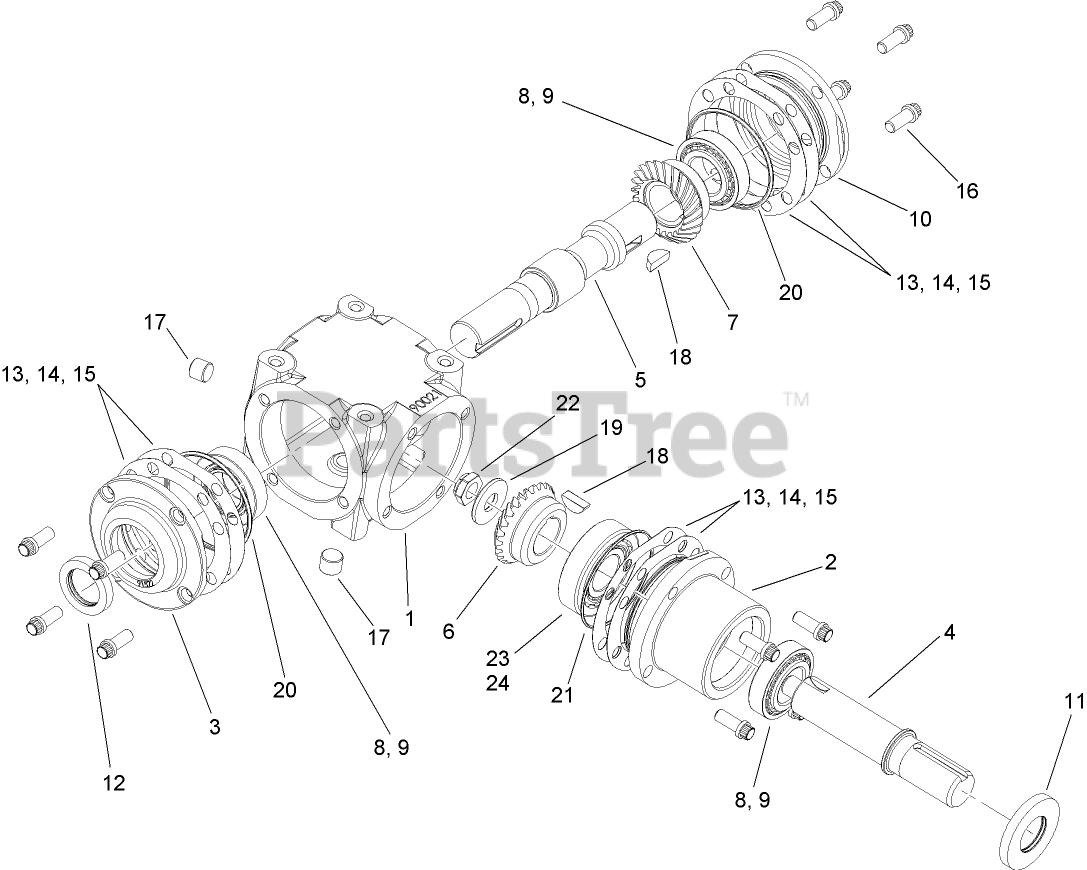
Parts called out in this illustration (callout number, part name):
2	HOUSING-PINION
3	CAP-END, OPEN
4	SHAFT-PINION
5	SHAFT-CROSS
6	GEAR-SHAFT, CROSS
7	GEAR-PINION
8	BEARING-CUP
9	BEARING-CONE
10	CAP-END, CLOSED
12	SEAL-SHAFT, CROSS
13	SHIM-BROWN, .010IN
14	SHIM-BLUE, .005IN
15	SHIM-GREEN, .003IN
18	KEY-WOODRUFF
19	WASHER
20	O-RING
21	O-RING
22	NUT LOCK
23	BEARING-CUP
24	BEARING-CONE
